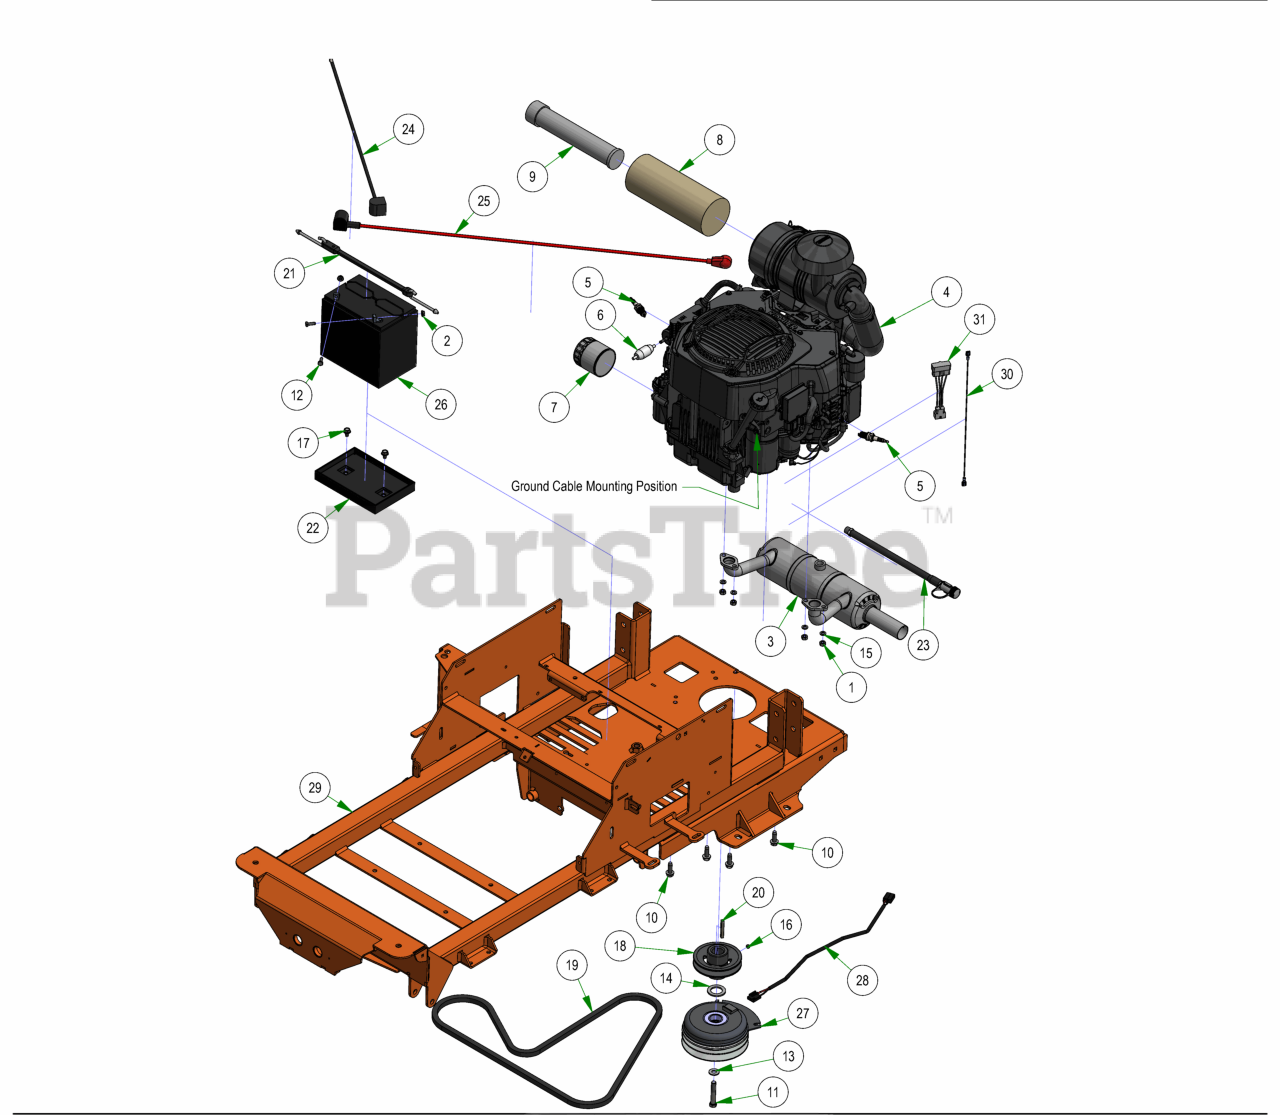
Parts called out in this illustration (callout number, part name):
1	M8-1.25 DIN 934 HEX NUT (CL.8) ZINC
2	1/4-20 HEX SERRATED FLANGE NUT HARD/ZINC
3	2023 ECV749 Maverick HD Muffler
4	Kohler Command 26.5hp EFI CV749
5	Spark Plug
6	25/26 HP Kohler Fuel Filter
7	Oil Filter
8	Canister Air Filter- Outer
9	Canister Air Filter- Inner
10	3/8-16 X 1-1/8 HEX WASHER UNSLOT SERRATED (TRI-LOB) TRS ZINC YELLOW
11	7/16-20 X 2.5" HEX Bolt GR.8 W/Patch
12	1/4-20 X 3/4 HEX CAP SCREW (GR.5) ZINC
13	3/8 FLAT WASHER USS (1" OD) ZINC
14	1.140 ID X 1.750 OD X .132 THICK FLAT WASHER PLAIN
15	5/16 SPLIT LOCKWASHER ZINC
16	5/16-24 X 1/4 SOCKET SET SCREW (CUP PT) PLAIN
17	5/16-18 X 1/2 HWH unslot (F) tcs zinc
18	4 3/4 Motor Pulley
19	75.8" Pump Belt
20	1/4 X 2 SQ MACHINERY KEY 1018 STL PLAIN
21	2023 Rubber Battery Hold Down Strap
22	Battery Tray
23	Kohler Oil Drain
24	24 inch Black Cable – MZ/ZT
25	36" Red Battery Cable
26	SP-35 Battery
28	Clutch Pigtail
29	2025 Maverick Frame
30	Compact Outlaw/Honda Starter Jumper Wire
31	2019 Harness Adaptor-Carbureted Yamaha
